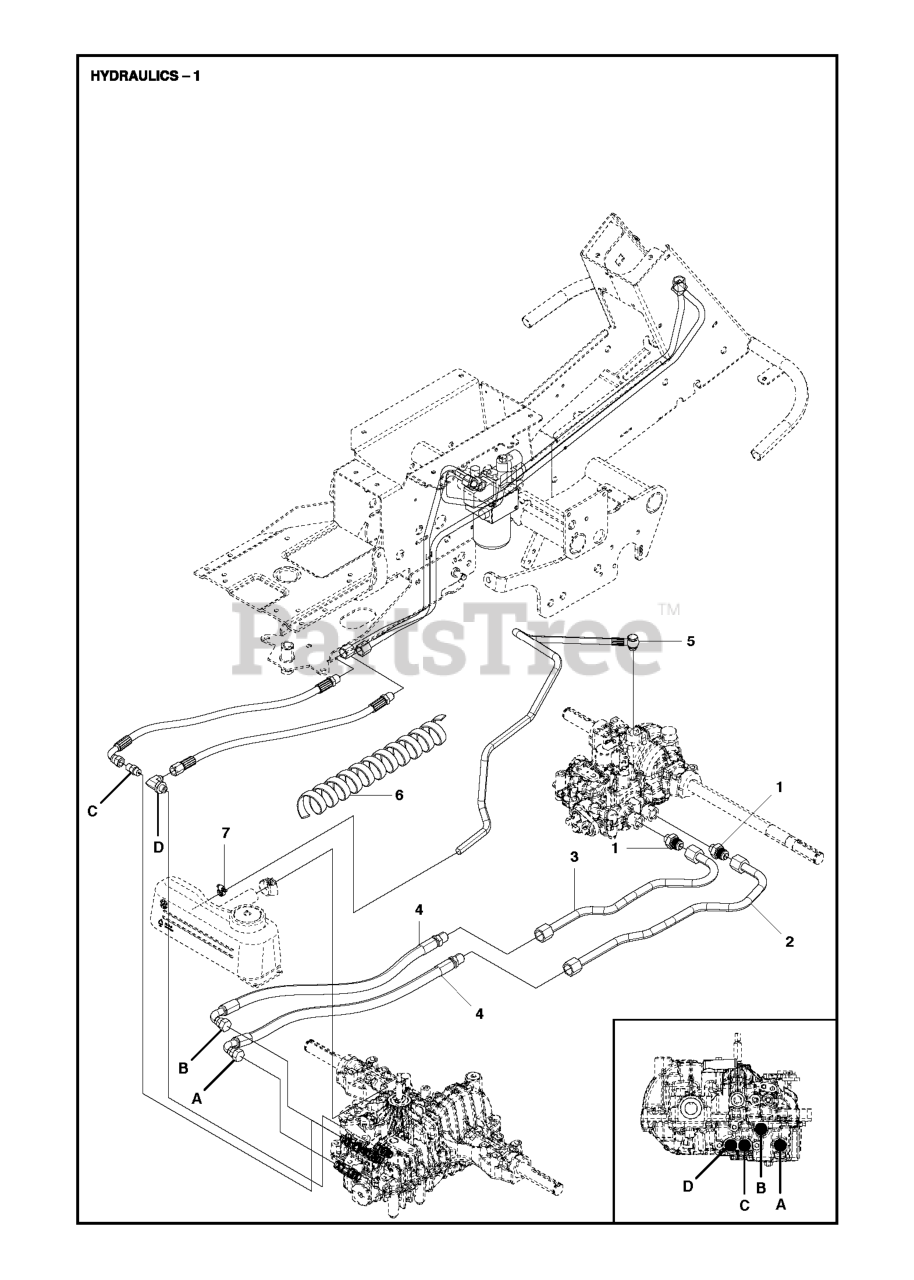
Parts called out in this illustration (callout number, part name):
1	PIPE FITTING
2	SPRING,BRAKE RETURN
3	PULLEY
4	RETAINING RING LT
5	STRAP TORQUE
6	HOSE GUARD
6	SCREW 5/16"
8	ROD SHIFT FENDER ADJUST LT
10	PIN COTTER
11	WASH-SHFT PLT LT
13	BOLT 1/4-28X3/4
14	LOCKWASHER
15	BOLT HEX 5/16-18 GR 5
16	NUT.71038.31-18.HEX.NYLOCK
19	NUT
21	KNOB T (1/2-HOLE)
22	ROD
24	NUT
25	SPRING ROD LT
26	WASHER
27	COTTER PIN
28	ROD, PARKING BRAKE
29	PLUNGER CAP
30	BRKT, MOUNT TRNSAXLE
34	SHAFT, FOOT PEDAL
35	BEARING.NYLON
37	DRIVE PIN
38	PULLEY.FLAT
42	WASHER
47	IDLER PULLEY
48	BELLCRANK, CLUTCH
49	RETAIN BELT
50	BOLT.3/8-16X1.50
53	LINK.CLUTCH.7.66.2005
55	SPRING, RETURN LT
56	SCREW.3/8-16
62	PEDAL COVER T
65	LOCKWASHER
66	KEEPER BELT ENGINE
77	SQUARE KEY
79	KEY STD (1373) DANA
82	SHIFT SPRING
83	WASHER
84	LINK.T/A.CRD.D6800.18"CLR
96	RETAINER M
120	NUT LOCK FLG 3/8-16 UNC
150	BUSHING.BELLCRANK.GRD.DR
151	WASHER 12/32X2X10GA
156	WASHER.SRRTD.5/16
158	BRACKET
159	RB HUB.SHIFT
161	BOLT
162	NUT.CROWNLOCK.1/4
165	RP BRACKET
166	CAPSCREW.HXHD.FLG.5/16-18X.625
167	BRACKET.SUPT.SHIFT.CRD
168	BOLT.SHOULDER.5/16-18X
181	BRACKET
182	BELT GUIDE
183	PULLEY.V-IDLER.GRND.DR
187	BOLT.5/16-18X1.25
203	BOLT.HEX.7/16-20 X 5
207	WASHER NYL
214	LEVER
254	SCREW 3/8-16X1
255	SHAFT
258	CLIP RETAINER
261	FLAT IDLER PULLEY
263	SCREW, 3/8-16X3/4
266	PROTECTOR
268	GUARD MUFFLER
275	WASHER
292	SPACER
293	BOLT.RDHD SQNK 3/8-16 X 3-1/2
294	NUT.HEX.3/8-16
295	PULLEY IDLER COMPOSITE
